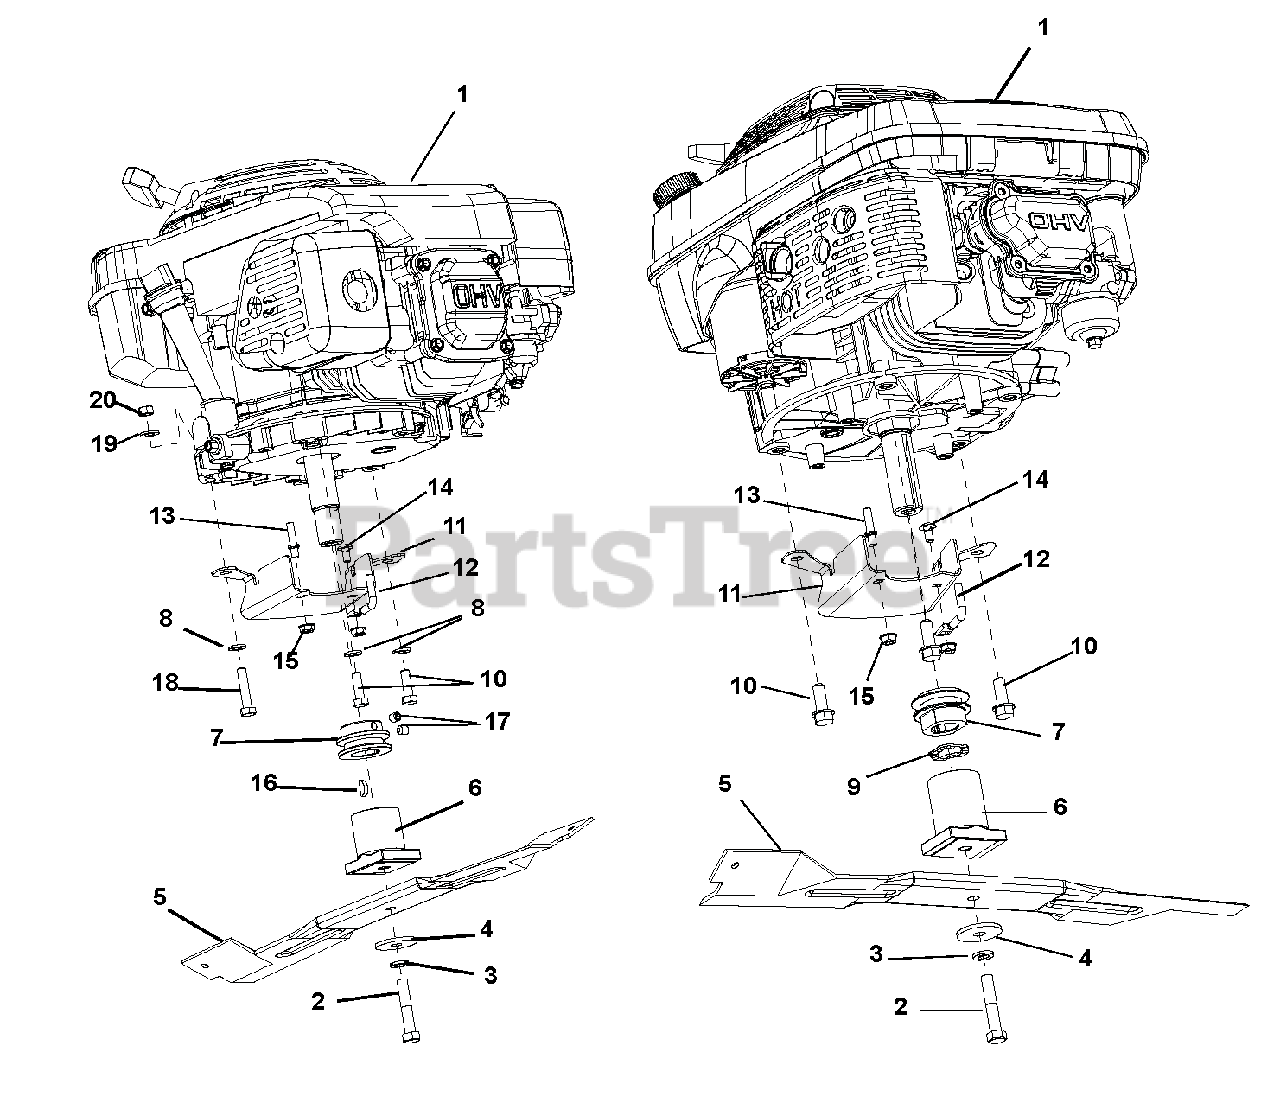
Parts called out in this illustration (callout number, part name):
1	6.0 HP KAWI U.S. COMMERICIAL
1	ENGINE - HONDA 5.5 HP OHV
2	BLT-HEX .38-24 X 2.00 GR8 YWZC
3	@WSHR-LK .38X.094 REG YWZC
4	WSHR-FL-STL .390X1.5X.125 YWZC
5	21" MOWER BLADE
6	ADAPTER, CE BLADE
6	ADAPTER - BLADE HUB
7	PULLEY-SINTERED IRON LM
7	PULLEY - UNV DRIVE - STEEL
8	@WSHR-LK .31X.078 REG YWZC
9	WASHER-WAVE .885X1.311X.125
10	@SCR-TAP .38-16X1.00 HWH TR YZ
10	BLT-HEX .31-24X1.00 GR5 YWZC
11	GUIDE-BELT
12	FINGER, BELT
13	FINGER, BELT
14	@BLT-RDHDSQNK .25-20X.50 G5YZ
15	@NUT-SPNLK-FLG .25-20 YWZC
16	KEY-WDRF .156X.625X.25 SAE 6
17	SCR-SET .31-18X.38 SKHCUPDL
18	BLT-HEX .31-24X1.50 GR5 YWZC
19	@WSHR-FL-STL.344X.688X.065YWZC
20	NUT-HEX .312-24 YWZC
